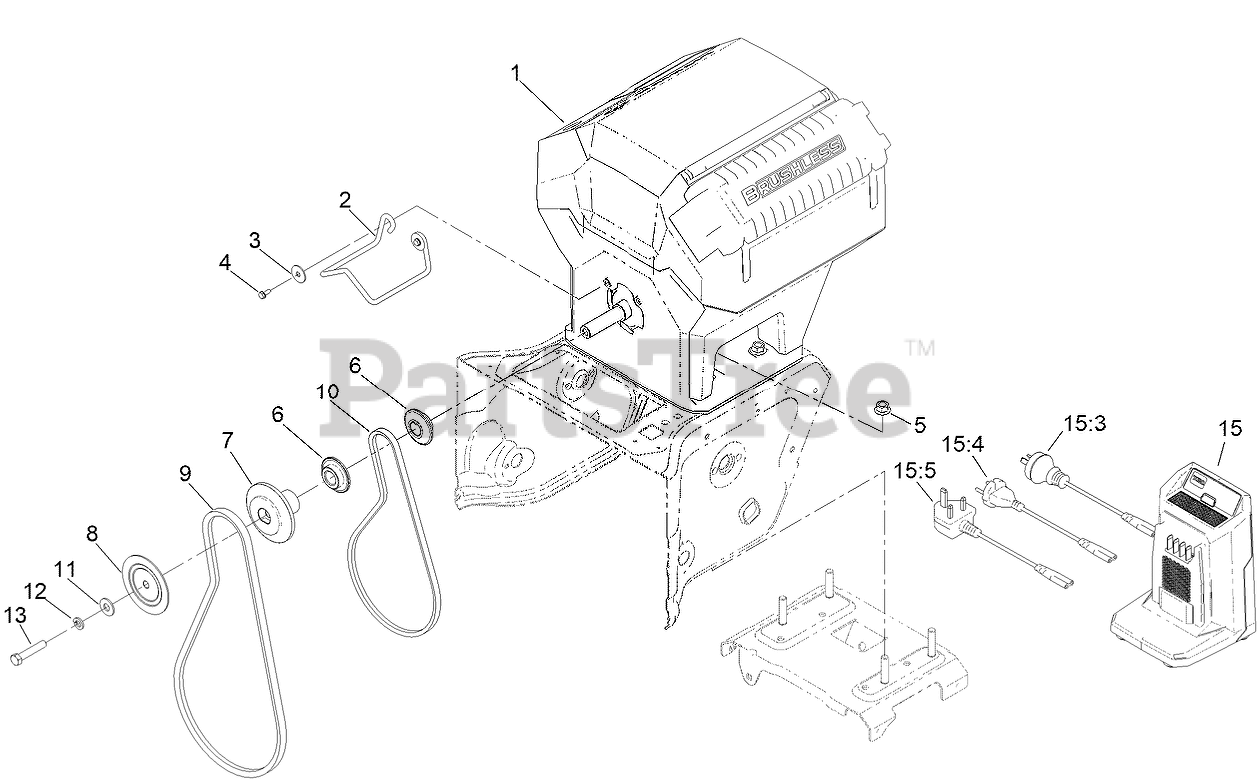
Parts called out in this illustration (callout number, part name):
1	POWERHEAD-60V
2	GUIDE-BELT
3	WASHER-FLAT
4	SCREW-TAPTITE
5	NUT-LOCK
6	PULLEY-ENGINE, TRACTION
7	PULLEY-AUGER, REAR
8	PULLEY-AUGER, FRONT
9	BELT-V
10	BELT-V
11	WASHER-PLAIN
12	WASHER-LOCK
13	SCREW-HH
15	CHARGER, RAPID 60V
15:3	CORD-CHARGER, AU/NZ
15:4	CORD-CHARGER, CE
15:5	CORD-CHARGER, UK
